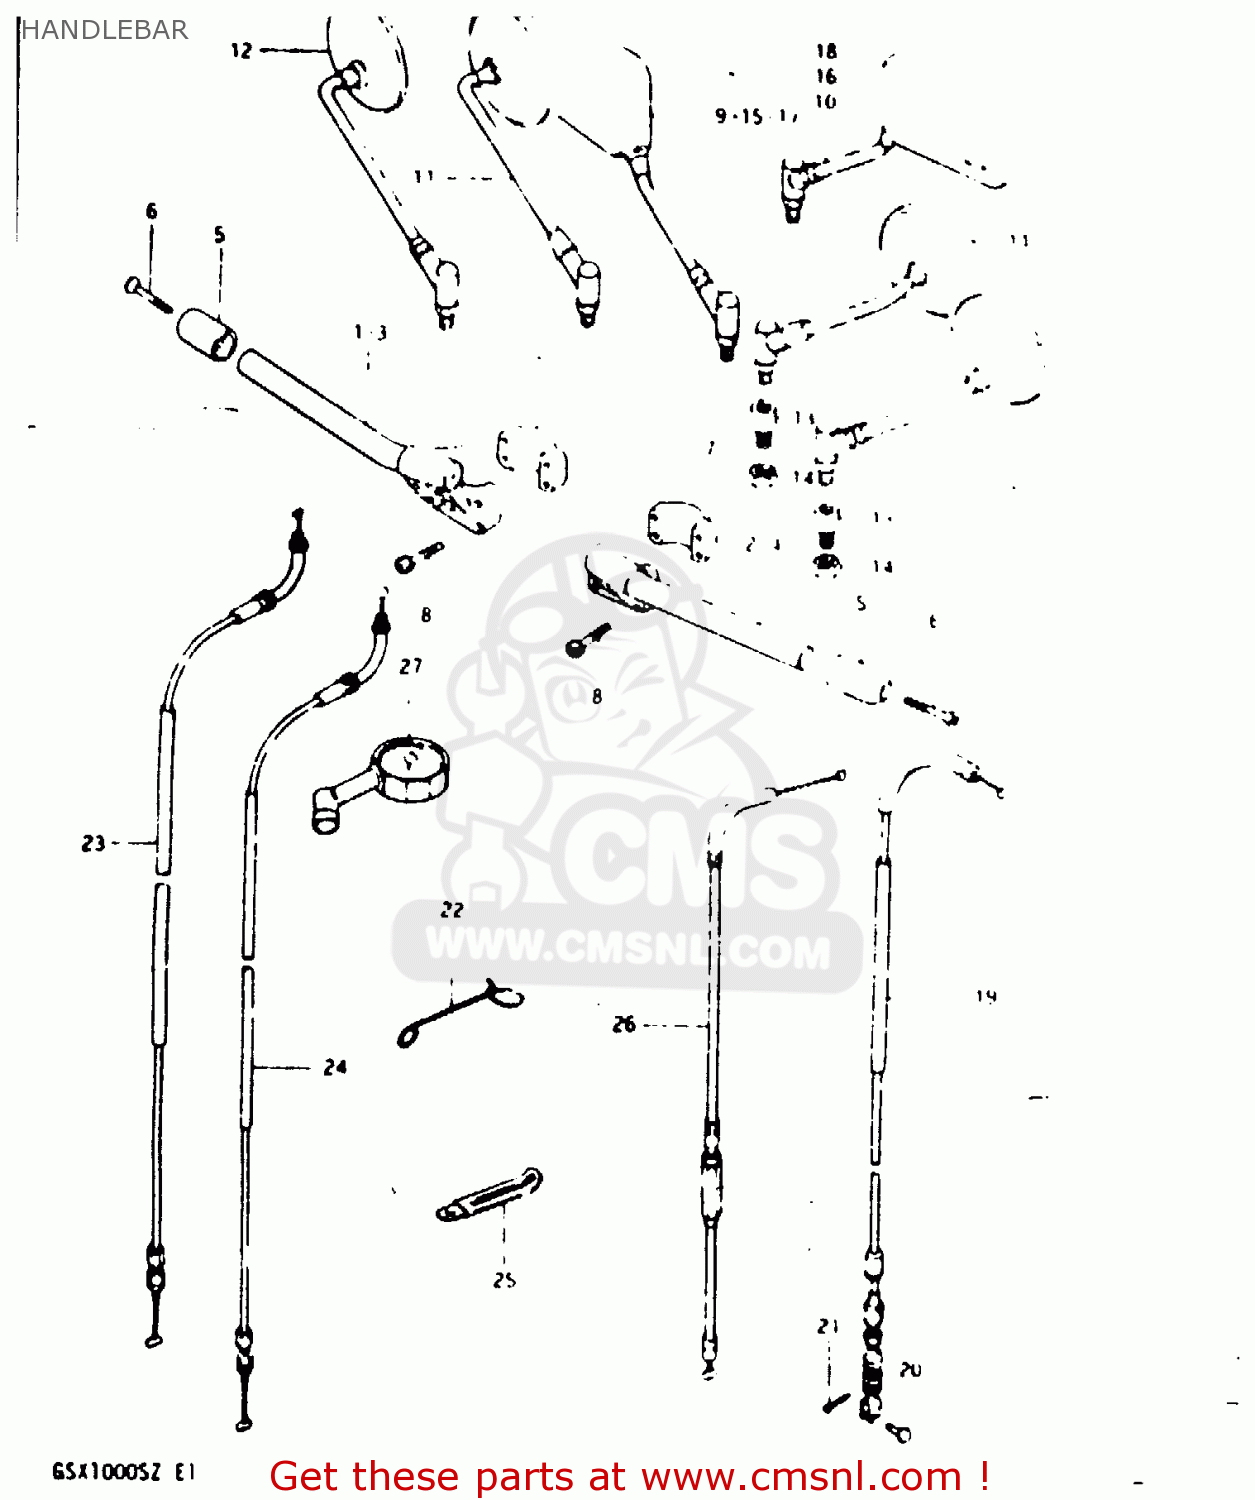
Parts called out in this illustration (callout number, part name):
3	HANDLEBAR,R
4	HANDLEBAR,L
5	BALANCER,HANDLEBAR
6	SCREW
7	HOLDER,HANDLEBAR
8	BOLT
11	MIRROR ASSY,RH
13	CUSHION,REAR VIEW MIRROR
14	NUT
19	CABLE, CLUTCH
20	PIN(L:15)
21	PIN
22	GUIDE,CLUTCH CABLE
23	CABLE, THROTTLE NO.1
24	CABLE, THROTTLE NO.2
25	CLAMP
26	CABLE,CLUTCH
27	GAUGE ASSY,AIR PRESSURE
